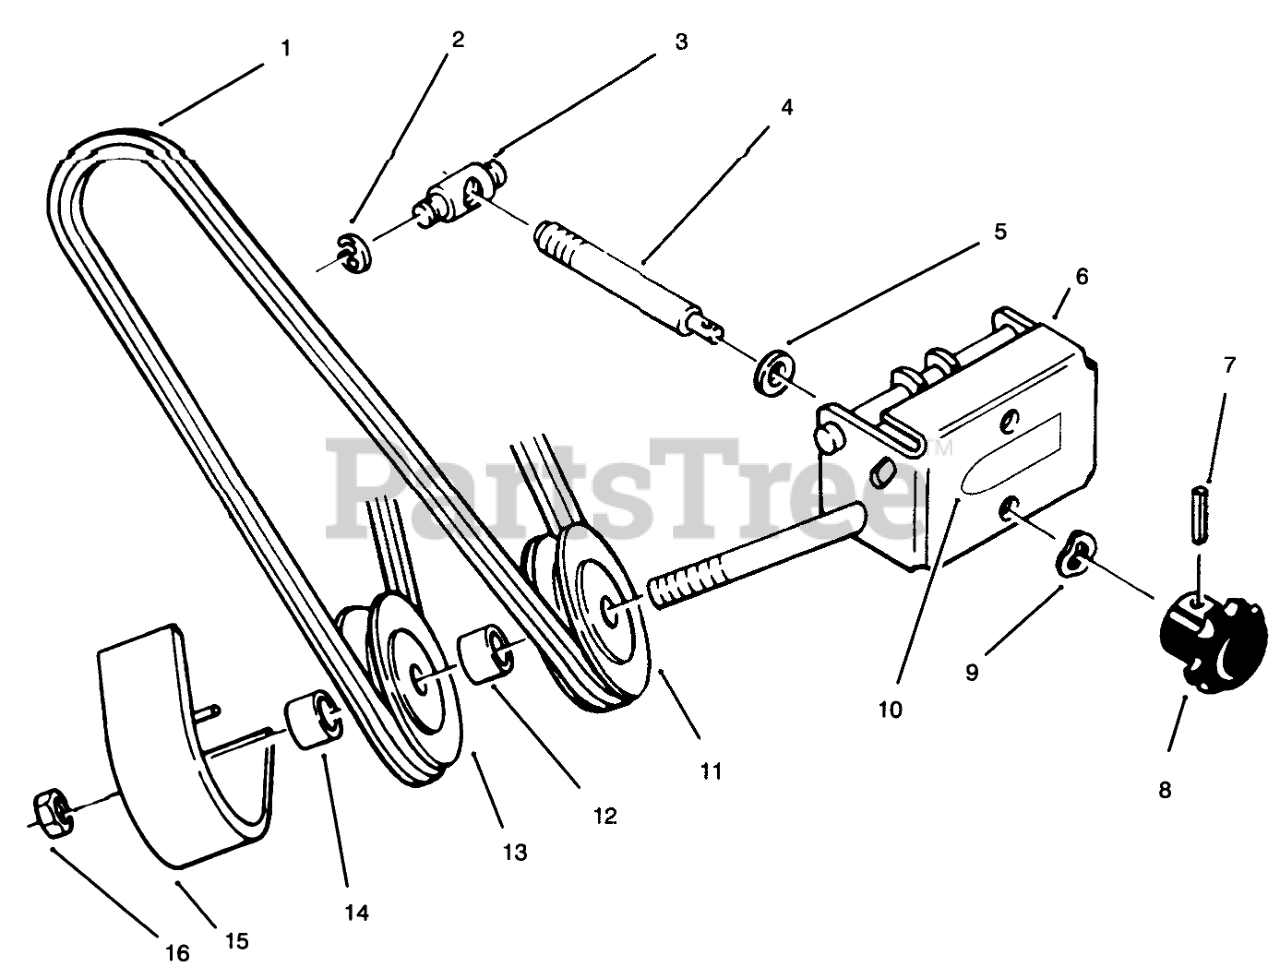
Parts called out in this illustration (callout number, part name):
1	V-BELT
2	RING-RETAINING
3	TRUNNION-DOUBLE
4	ROD ADJ
5	WASHER-FLAT
6	Front Support
7	PIN-ROLL
8	KNOB-ADJUSTMENT
9	WASHER-SPRING
10	DECAL-ATTACH A-MATIC
11	PULLEY-IDLER
12	SPACER
13	PULLEY-FLAT IDLER
14	SPACER-OUTER
15	Belt Cover
16	Nut
